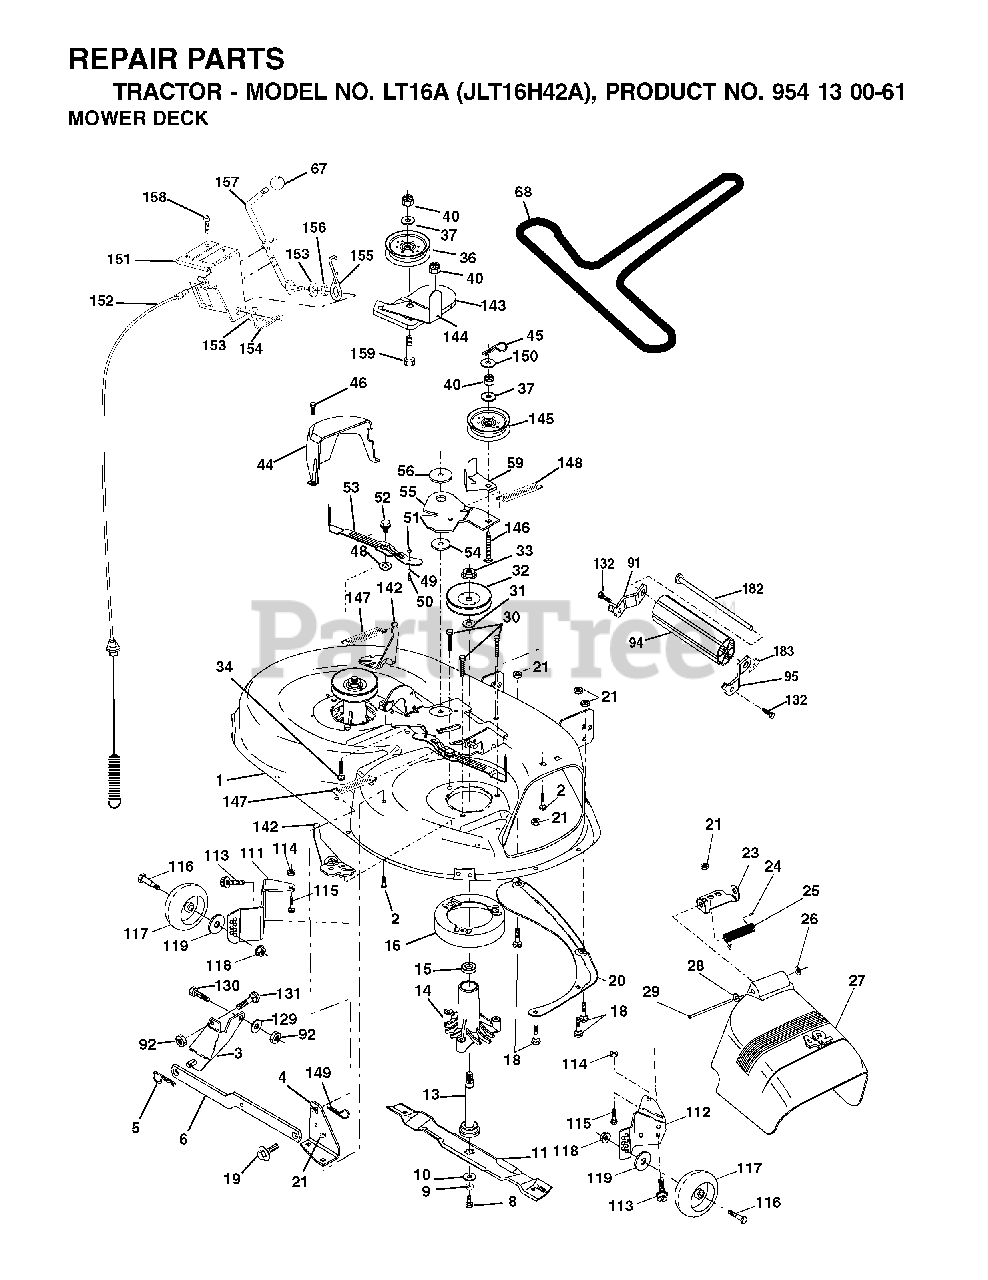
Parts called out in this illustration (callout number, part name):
1	42" DECK KIT
2	BOLT
3	BRKT ASM SWAY BAR
4	BRACKET SWAY BAR 42" DECK
5	RETAINER-SPRNG RB
6	BAR SWAY DECK
8	BLADE BOLT
9	LOCKWASHER
10	WASHER.BLADE
11	BLADE 42"
13	SHAFT ASM VENT
14	HSG MANDREL
16	STRIPPER, MWR ROUND
18	BOLT
19	BOLT SHD 5/16-18
20	BAFFLE.VORTEX
21	LOCKNUT
23	BRKT, DEFL. MOWER
24	CAP-SLEEVE LT
25	SPRING TORSION
26	NUT PUSH M
27	SHIELD DEFLECTOR
28	WASHER
29	ROD.HINGE
30	SCREW, WASHER HEAD
31	WASHER
32	PULLEY/MANDREL
33	NUT, FLG TOPLOCK 9/16"
34	BOLT
36	FLAT IDLER PULLEY
40	LOCKNUT
44	GUARD MANDREL LH BLACK
45	RETAINER M
46	SCREW.1/4-20X5/8
49	ROLLER ASM CAM FOLLOWER
50	BOLT
53	ARM
54	HARDENED WASHER
55	ARM IDLER 42" MOWER LT/YT
56	SPACER.RETAINER.MOWER
59	GUARD, BELT
67	KNOB T (3/8 HOLE)
91	BRACKET ASM NOSEROLLER LH
92	NUT
94	NOSE ROLLER
95	BRACKET ASM NOSEROLLER RH
111	BRACKET, WHEEL
112	BRACKET, WHEEL
113	SCREW 5/16-18X1/2"
114	NUT
115	BOLT
117	WHEEL.GAUGE.STANDARD
118	LOCKNUT
119	WASHER
129	WASHER
131	BOLT D
132	SCREW 3/8-16X3/4
142	ARM SPRING BRAKE MOWER
143	BRACKET, ARM IDLER
144	KEEPER.BELT.42".CLUTCH.CABLE
145	PULLEY
146	BOLT, CARRIAGE IDLER BLACK
148	IDLER RETURN SPRING
149	SPRING.RETAINER.YELLOW.ZINC
150	WASHER PM
151	BRACKET, CLUTCH CABLE
152	42" CLUTCH CABLE
153	WASHER FLAT 3/8"
154	SPRING RETAINER
155	SPRING RETENTION LEVER
156	SPACER CLUTCH CABLE
157	ROD CLUTCH CABLE 3/8"
158	SCREW
159	BOLT
160	SCREW 3/8-16X3/4
182	ROD ROLLER NOSE STANDARD
183	SPRING RETAINER
